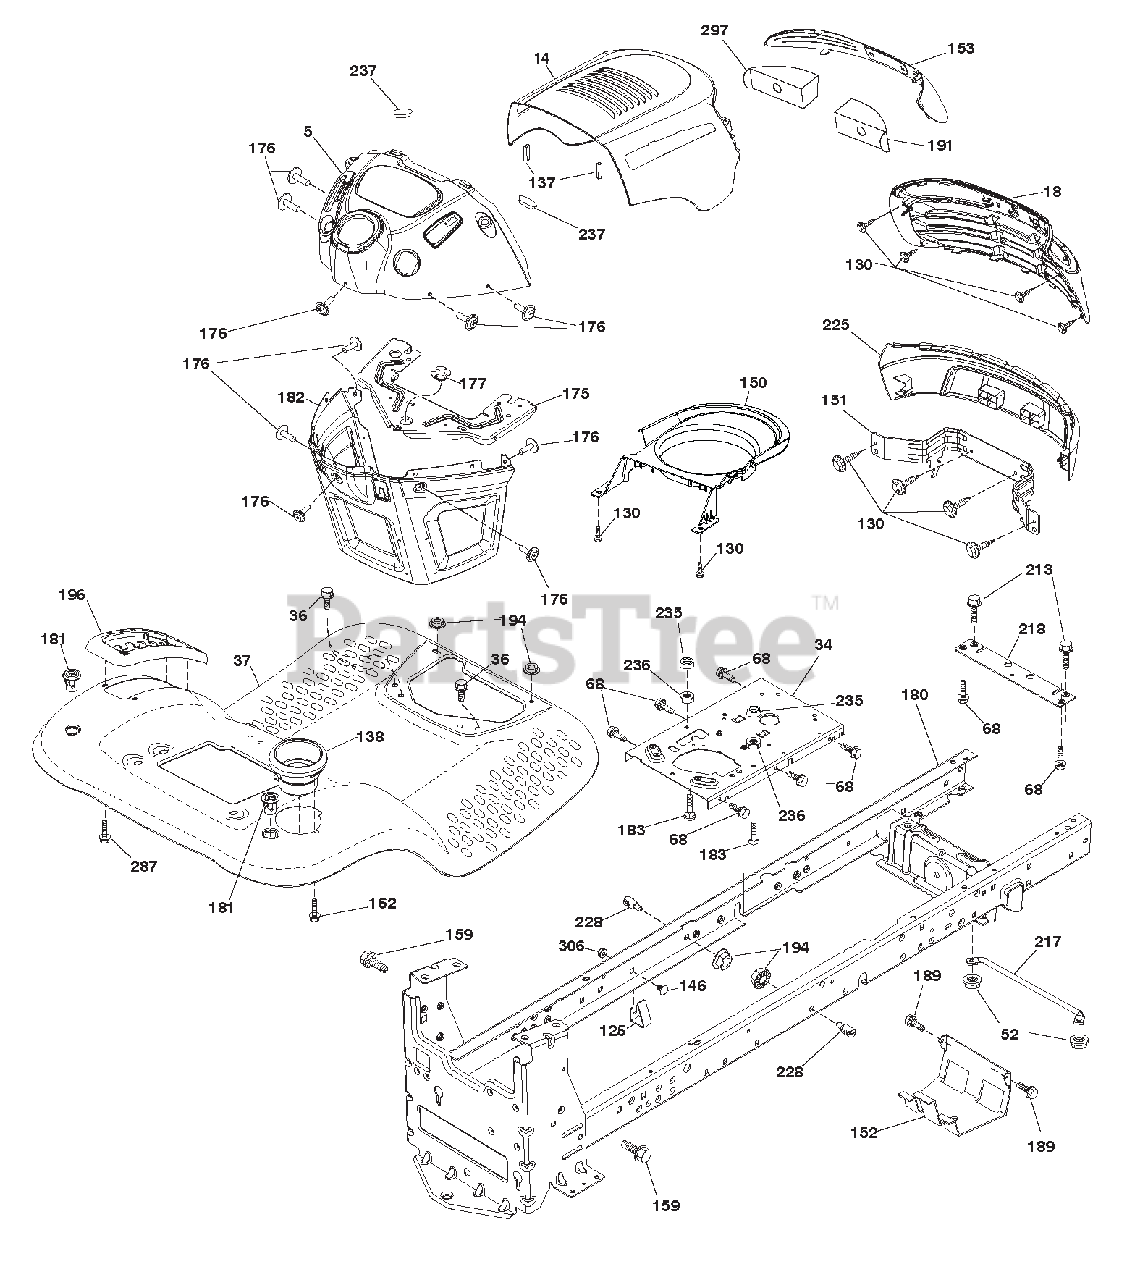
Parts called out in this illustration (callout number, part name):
5	DASH.P/L.TEX.CABLE
18	GRILLE
34	PLATE ENGINE WELDED CHASSIS
36	SCREW.5/16-18X3/4.SMGML.TAP/R
37	FENDER TLT W/CPH W/FW 422
52	Nut, Hex, Crownlock 5/16-18
68	SCREW.THDROL.5/16-18 X 1/2TYTT
125	CLIP.FUEL.LINE
137	BUMPER HOOD
138	CUPHOLDER TL TEX 428
150	AIR DUCT.INTAKE.B&S
151	Bracket Pivot
152	SHIELD.BROWNING.W/TEX
153	LENS, ARIENS
159	SCREW.HEXWSH THDR3/8-16X3/4.BL
162	SCREW.HEX.WSH.HI-LO.1/4X1/2UNC
175	CROSSMEMBER.LT
176	SCREW.#10-24X5/8.RND.QUDRX.GIM
177	BUSHING.STEERING.LT
180	CHASS WLDMT TL 12 GA/2PC 18/22
181	BUSHING MNT FEND CRGO BLK TEX
182	DASH LOWER
183	BOLT.FIN.HEX.5/16-18 UNC X1-1/
189	SCREW.5/16-18X3/4.SMGML.TAP/BL
191	INSERT REFLECTIVE RH
194	Nut, Lock Hex Flange 5/16-18 u
196	CONSOLE ASM.DECKLFT.BL/RBT.TLT
213	BOLT.HEX.HD.1/4-20UNC X 3/4
217	ROD.PIVOT.HOOD
218	X-PIECE.HOOD.STOP.NON/STEALTH
225	BUMPER
228	STUD.FASTNER.W/'D'ANTI-ROTATIO
235	SPACER.FENDER
236	NUT.CENTER LOCK.5/16-18 UNC
237	PLUG.MOUNT.CARGO
287	SCREW.HEX.WASHEAD.1/4-20 X 3/8
297	INSERT REFLECTIVE LH
306	Nut, Hex, Flangelock 3/8-16
